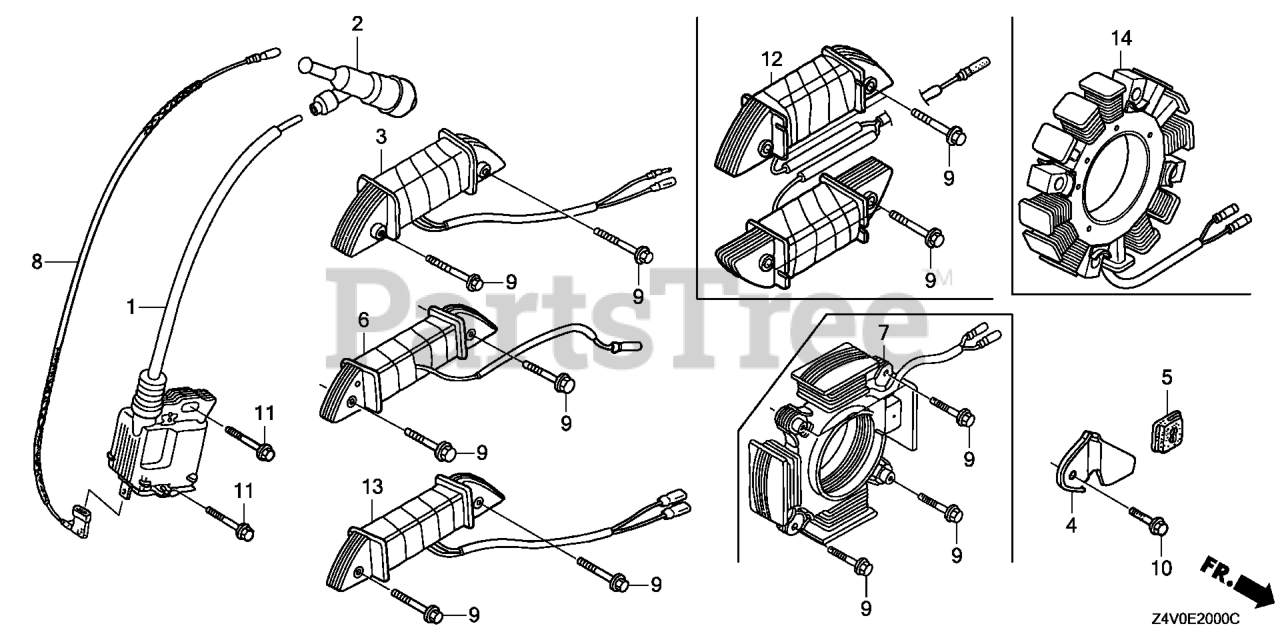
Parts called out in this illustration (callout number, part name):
1	COIL ASSY., IGNITION (TEC)
2	CAP ASSY., NOISE SUPPRESSOR (NGK)
2	CAP ASSY., NOISE SUPPRESSOR (TEC)
8	WIRE, STOP SWITCH (370MM)
11	BOLT, FLANGE (6X25) Use up to Engine SN 2056819.
